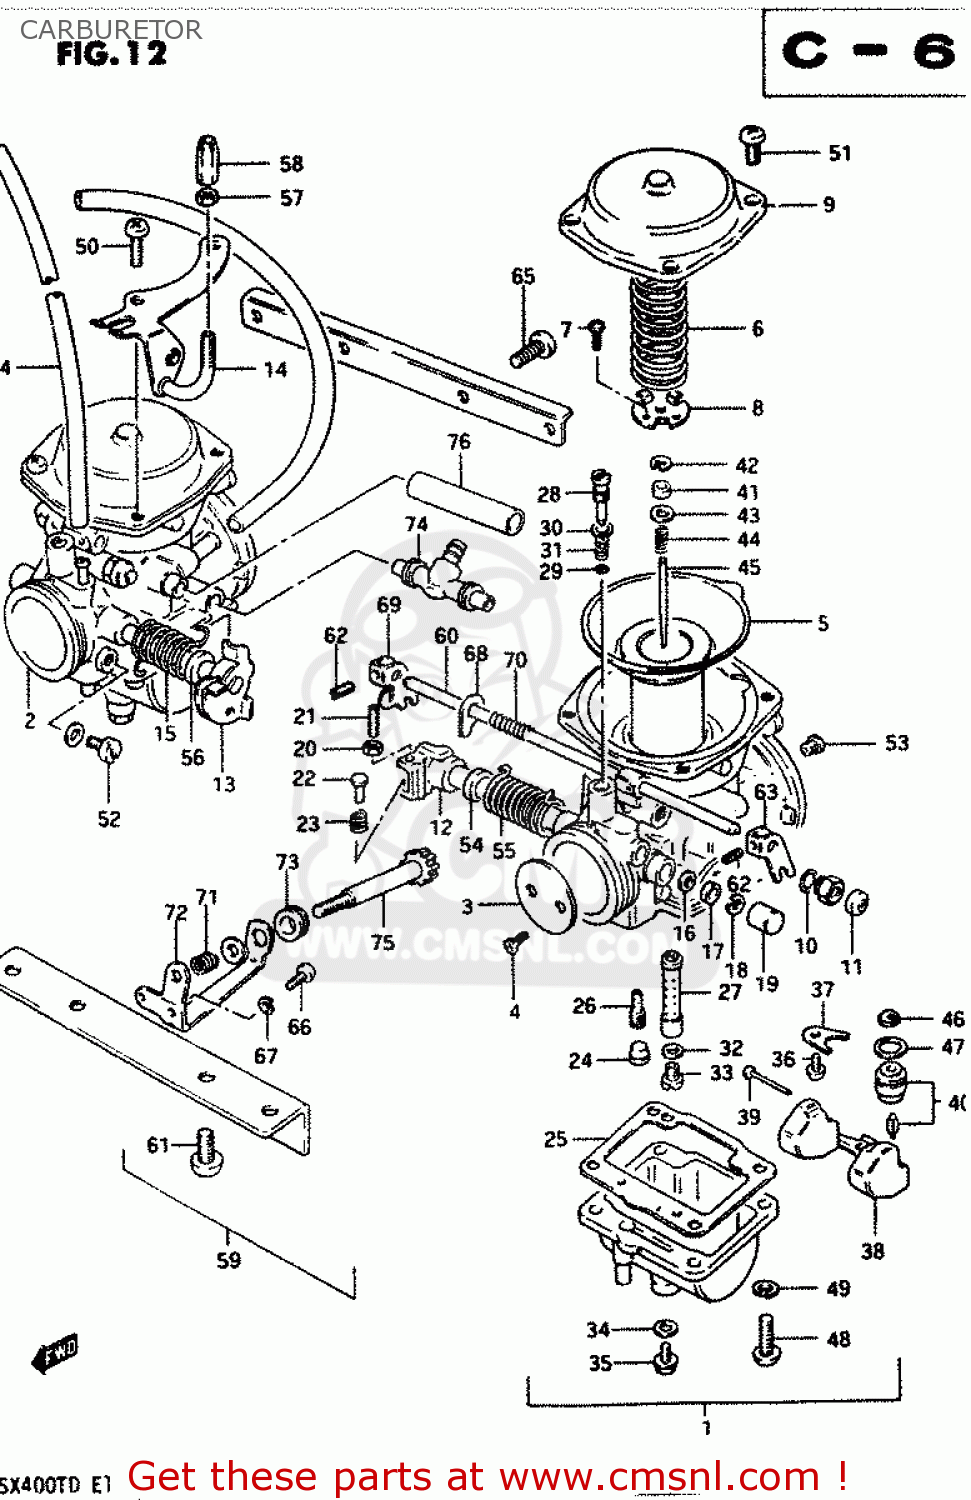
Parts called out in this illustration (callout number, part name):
1	CARBURETOR, LH
2	CARBURETOR, RH
3	VALVE,THROTTLE
4	SCREW
5	DIAPHRAGM,CARBURETOR
6	SPRING
7	SCREW
8	PLATE
9	COVER, DIAPHRAGM
10	O RING
11	CAP,STARTER VALVE
12	SHAFT ASSEMBLY
13	SHAFT,THROTTLE
14	BRACKET
15	SPRING
16	SEAL
17	GASKET,THROTTLE SHAFT (NAS)
18	E RING
19	CAP
20	NUT
21	SCREW
22	PIN,THROTTLE LEVER
23	SPRING,THROTTLE SCREW
24	PLUG,NEEDLE JET
25	GASKET,FLOAT CHAMBER (NAS)
26	JET,PILOT(42.5)
27	JET,NEEDLE(P-1)
28	SCREW,PILOT AIR
29	O-RING
30	GASKET
31	SPRING
32	WASHER,NEEDLE NOZZLE
33	JET
34	GASKET (NAS)
35	PLUG,DRAIN
36	SCREW 4X6
37	PLATE,NEEDLE VALVE FITING
38	FLOAT
39	PIN,FLOAT
40	VALVE ASSEMBLY,NEEDLE
41	RING
42	CLIP
43	PIN,FLOAT
44	SPRING
45	NEEDLE,JET
46	FILTER
47	O-RING,NEEDLE VALVE
48	SCREW
49	LOCK WASHER
50	SCREW
51	SCREW
52	SCREW
53	JET
54	SPACER,THROTTLE SHAFT
55	SPRING
56	SPACER,THROTTLE SHAFT
57	NUT
58	ADJUSTER
59	FLANCE ASSY
60	SHAFT,STARTER
61	SCREW 6X12
62	SCREW
63	LEVER
64	HOSE
65	SCREW
66	SCREW
67	LOCK WASHER
68	PLATE
69	LEVER,STARTER
70	SPRING,STARTER
71	SPRING,THROTTLE ADJUST
72	BRACKET,THROTTLE ADJUST
73	CAP,RUBBER
74	NIPPLE,CARBURETOR
75	SCREW
76	HOSE
